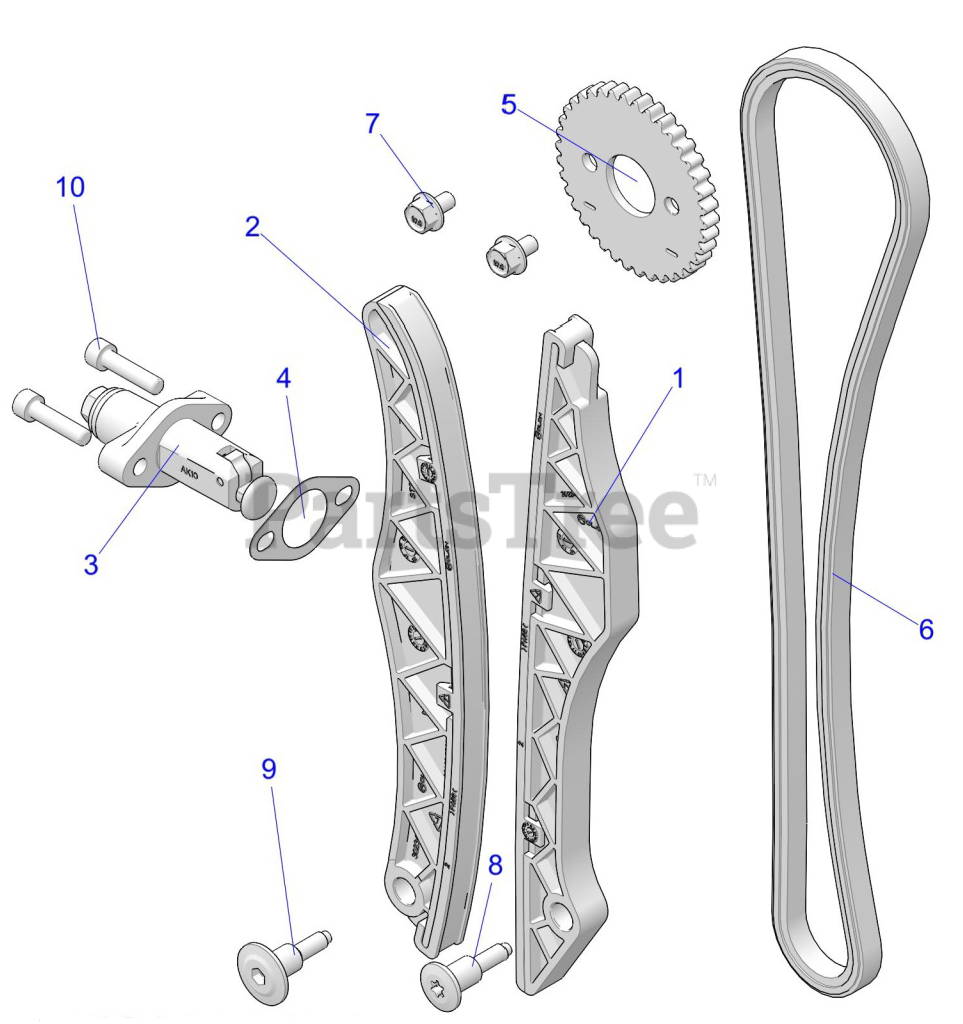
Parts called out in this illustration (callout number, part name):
1	GUIDE-CAM CHAIN- FIXED- SOHC
2	GUIDE-CAM CHAIN-TENSIONER-SOHC
3	TENSIONER-RATCHETING-MECH
4	GASKET-TENSIONER
5	SPROCKET-CAM- DRIVEN- SOHC
6	CHAIN-CAMSHAFT
7	SCR-HXFL-M6X1.0X10 10.9
8	BOLT-SHLDR-M6X12X15
10	SCR-SH-M6X1.0X25 10.9 ZPC D204
